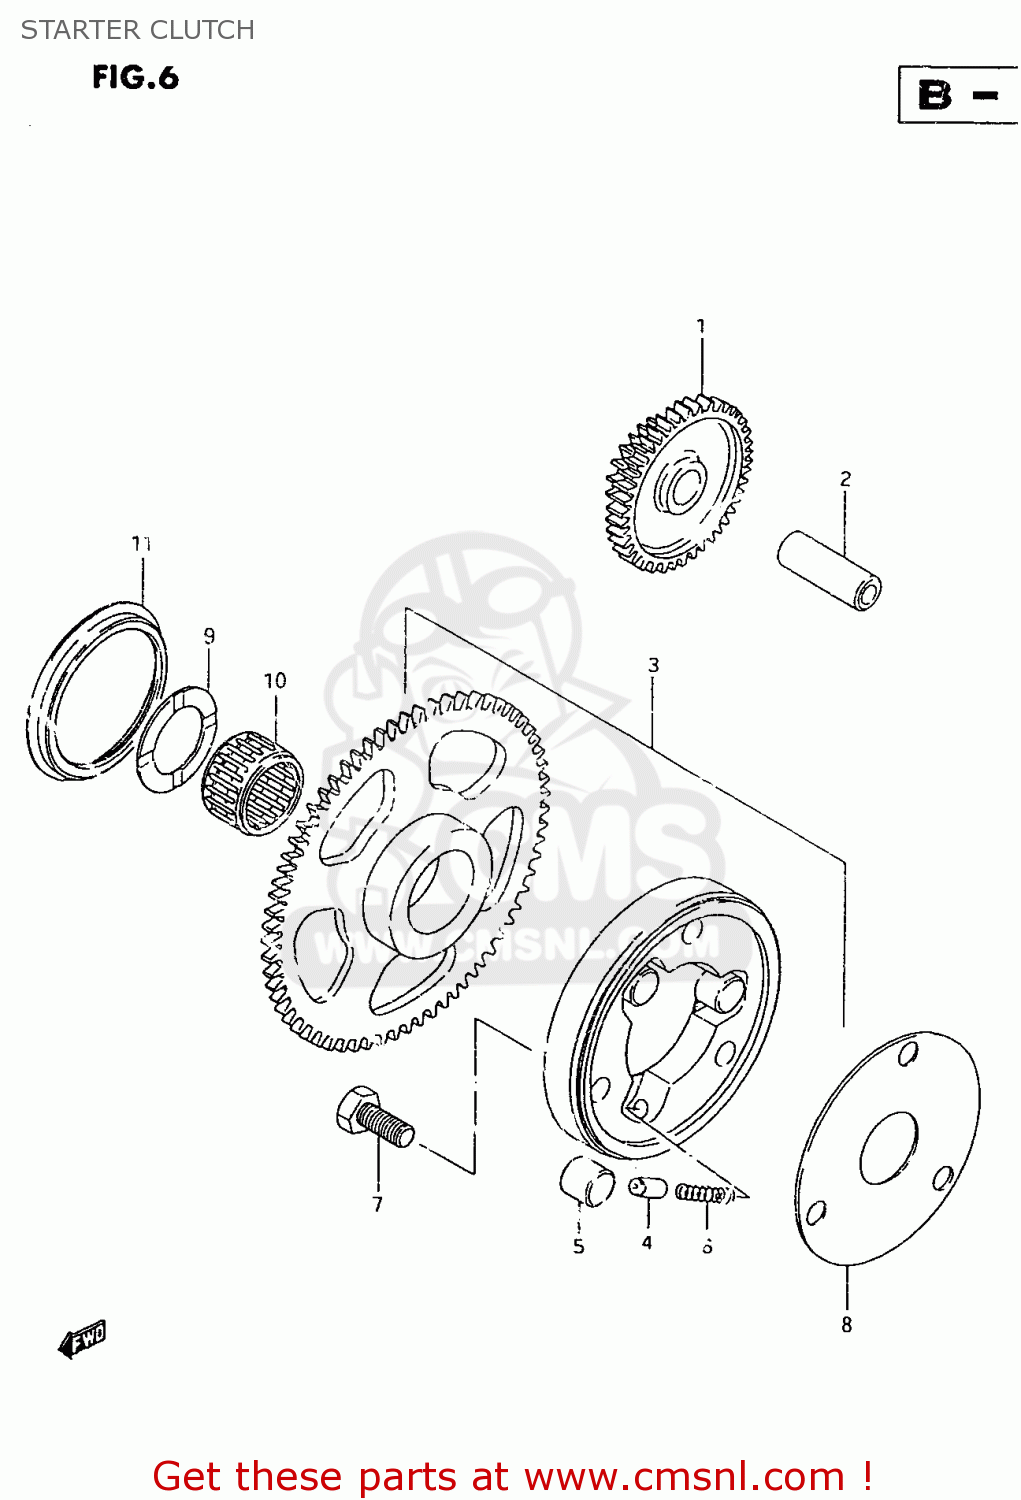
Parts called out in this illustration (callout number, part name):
1	GEAR,STARTER IDLE
2	PIN(7.4X13X40)
3	CLUTCH SET,STARTER
4	PIECE,PUSH
5	PIN(14X13)
6	SPRING
7	BOLT
8	SHIM,STARTER CLUTCH HUB
9	WASHER(27X40X2.5)
10	BEARING(27X32X21.8)
11	SEAL,OIL(52X62X6.8)
